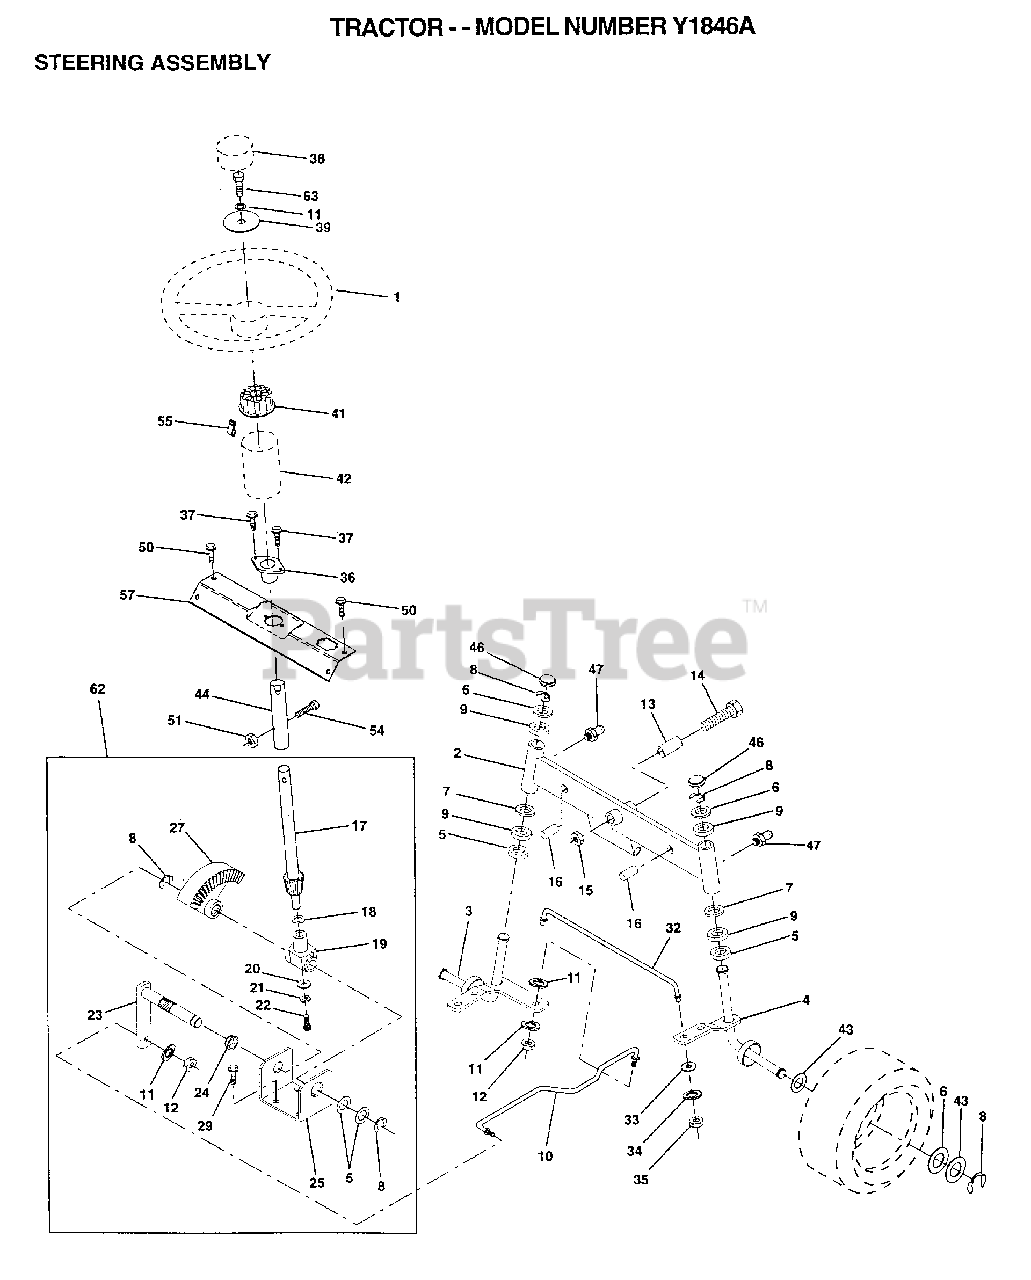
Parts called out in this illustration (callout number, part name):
1	CAP
2	RING
3	WASHER
4	COL. SRTG. BEAR.
5	AXLE ASM FRONT
6	WASHER .T
7	SPINDLE ASM RH
8	WASHER
9	COTTER PIN
10	WASHER
11	BUSHING.DRAGLINK
12	TIE ROD
13	SPINDLE ASM LH
14	BOLT HEX 5/8-11
15	"NUT-LOC,FLANGE LT"
16	BEARING
17	ZERK M
18	WASHER
